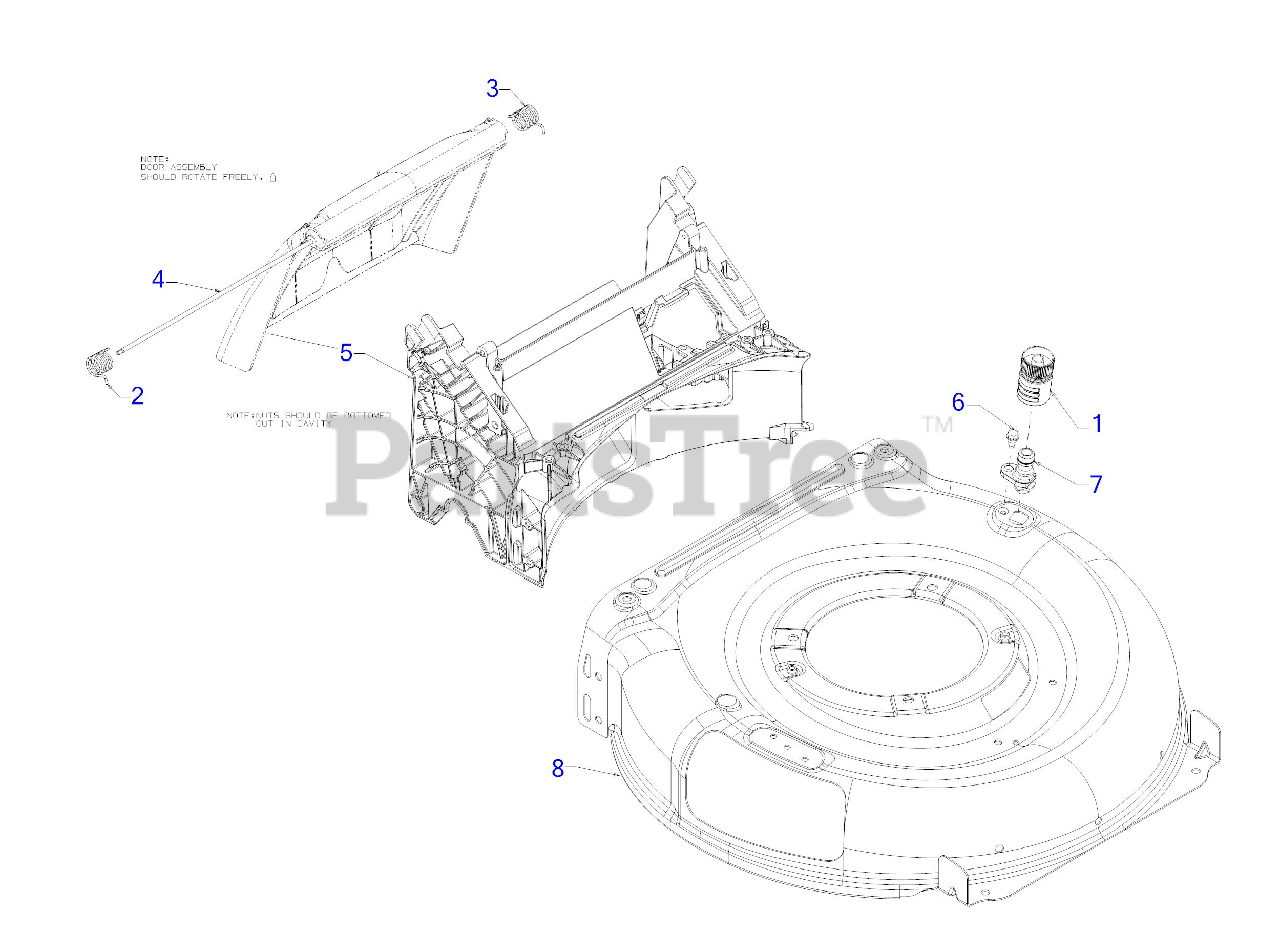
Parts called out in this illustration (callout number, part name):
1	WATER NOZZLE
2	TORSION SPRING (RH)
3	TORSION SPRING (LH)
4	REAR DOOR PIVOT ROD
5	REAR BAFFLE ASSEMBLY
6	SHOULDER SCREW 1/4-20 x .50
7	DECK WASH NOZZLE
